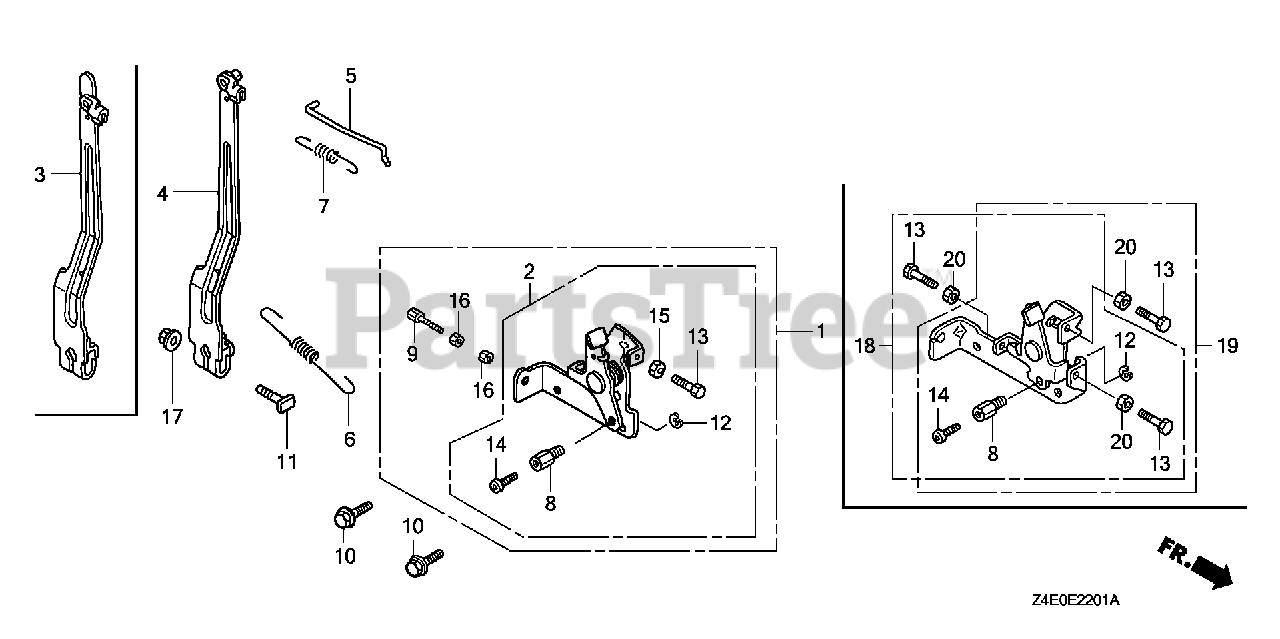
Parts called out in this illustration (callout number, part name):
2	CONTROL ASSY.
4	ARM, GOVERNOR
5	ROD, GOVERNOR
6	SPRING, GOVERNOR
7	SPRING, THROTTLE RETURN
8	HOLDER, WIRE
10	BOLT, FLANGE (6X14)
11	BOLT, GOVERNOR ARM
12	CIRCLIP (5MM) Use from Engine SN 2327377.
13	BOLT, HEX. (5X20)
14	SCREW, PAN (4X6)
15	NUT, HEX. (5MM)
17	NUT, FLANGE (6MM)
